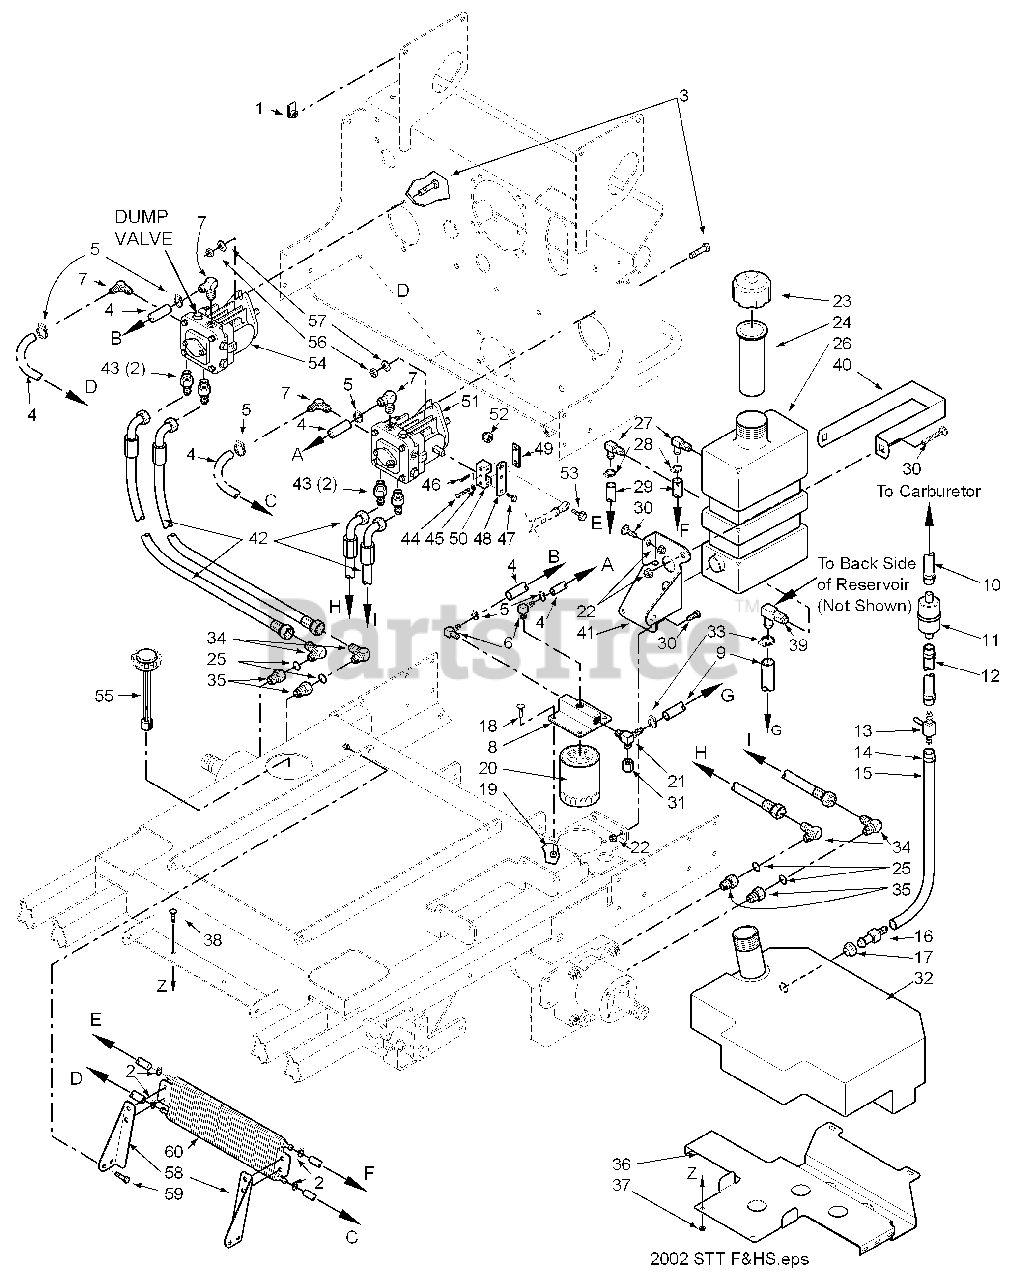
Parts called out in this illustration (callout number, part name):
1	U-Nut 1/4-20
2	Hose Clamp, 0.69 dia.
3	Bolt, Hex Head 1/4-20 x 2.0"
4	Hose, 3/8" ID Pushlock -
5	Clamp, Hose 1/2"
6	Elbow, 90 Degree - 1/4 NPT x 3/8 Hose
7	Elbow, 90 Degree - 9/16 O-ring x 3/8 Hose
8	Oil Filter Base
9	Hose Assembly, 1/2" ID
10	Fuel Hose to Carb.
11	Fuel Filter
12	Fuel Hose, 1/4" ID.
14	Clamp, Fuel Hose
15	Fuel Hose, 1/4" ID.
16	Hose Fitting
17	Bushing
18	Bolt, Hex Head 5/16-18 x1.0" Zinc
19	Nut, Serrated Flange 5/16-18
20	Oil Filter
21	Tee, 3/4 O-ring x JIC x 1/2" Hose
22	Nut, Hex Elastic Stop 1/4-20
23	Cap, Hydraulic Tank
24	Insert, Filler Neck
25	O-Ring
26	Oil Reservoir Assembly
27	Elbow, 90 Degree, 9/16-18 JIC x 9/16 O-Ring
28	Hose Clamp, 0.69 dia.
29	Hose, 3/8" ID, Pushlock
30	Screw, Phillips Head, 1/4-20
32	Fuel Tank Assembly
33	Clamp, Hose
34	Elbow, 90 Degree, 7/8-14 THD
35	Bushing, 7/8-14 JIC x 3/4-16 O-Ring
36	Support Bracket, Fuel Tank
37	Nut, 5/16-18 Serrated Flange
38	Bolt, Carraige 1/4-20 x 3/4"
39	Elbow, 90 Degree
40	Strap, Hydraulic Tank
41	Support Bracket, Hydraulic Tank
42	Hose Assembly, Pump
43	Union, 3/4-16 JIC x 3/4-16 O-ring
44	Bolt, Hex Head, 1/4-20 x 1-14"
45	Lockwasher, 1/4" Spring
46	Roll Pin, Spring 3/16 x 3/4"
47	Bolt, Hex Serrated Flange, 1/4-20 x 3/4"
48	Lever, Control
49	Clamp Plate, Pump Control
50	Block, Pump Control
51	Pump, Left Hand, BDP-10A 464
52	Nut, Hex, Elastic Stop 3/8-16
53	Bolt, Hex Head, 3/8-16 x 1-1/4
54	Pump, Right Hand, BDP 110A 464
55	Cap, Fuel Tank W/Guage
56	Nut, Hex Elastic Stop 3/8-16
57	Flatwasher, 3/8" Grade 8
58	Mounting Bracket - LH, Oil Cooler
59	Bolt, Hex Head 5/16-18 x 3/4"
60	Cooler, Oil
61	Clamp, .69 Dia.
